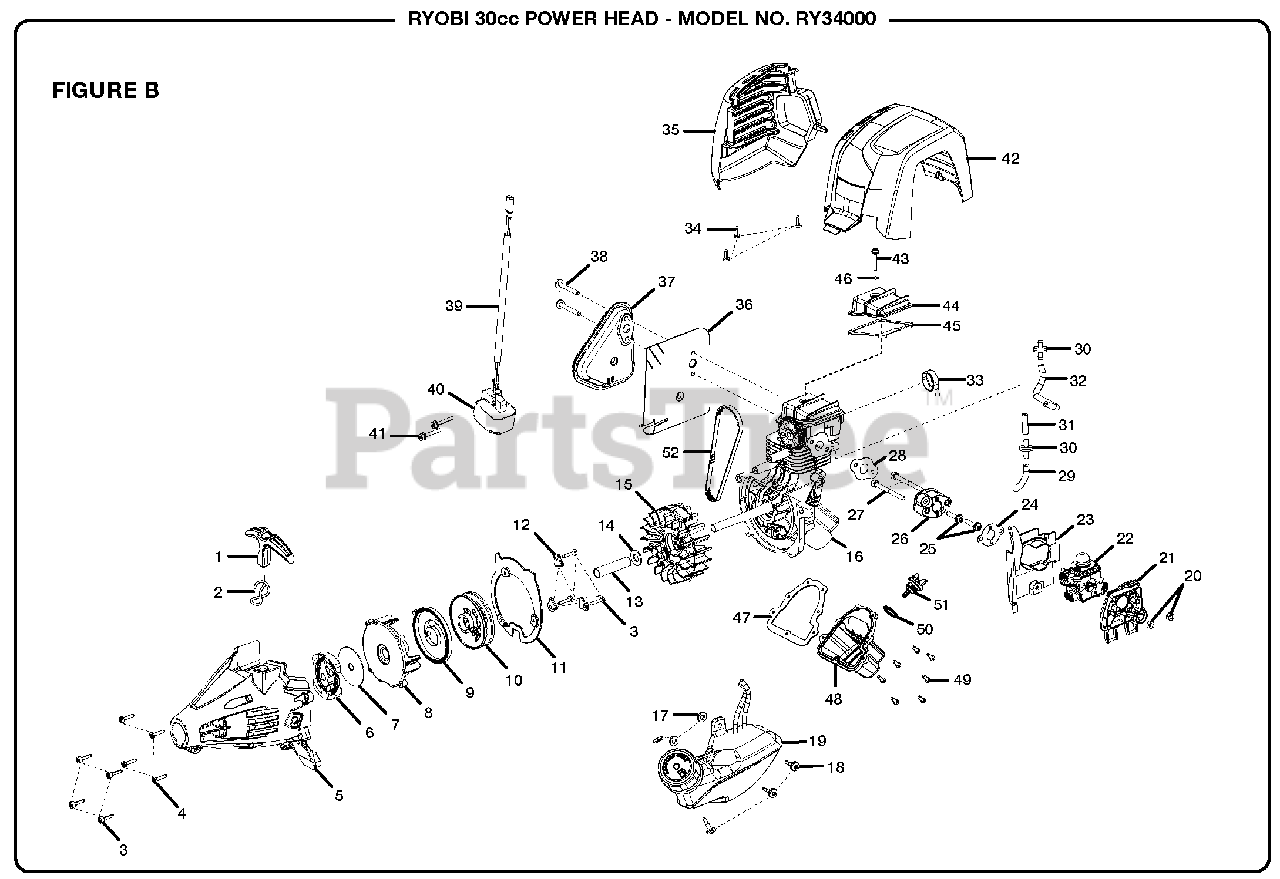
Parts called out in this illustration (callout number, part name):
1	Starter Grip
2	Starter Rope
3	Screw (M4 x 18 mm)
4	Screw (M4 x 16 mm)
5	Starter Housing Assembly
6	Clutch Assembly
8	Starter Baffle
9	Spring & Container
10	Easy Starter Assembly
12	Pulley Retainer
13	Spacer Tube
14	Washer
15	Flywheel Assembly
16	Short Block Assembly
18	Screw (M4)
19	Fuel Tank & Cap Assembly
20	Hex Nut (M5 x 0.8)
21	Air Filter Base
22	Carburetor Assembly
23	Air Baffle
24	Carburetor Gasket
25	Screw (M5 x 23 mm)
27	Bolt (M5 x 63 mm)
28	Heat Dam Gasket
29	Breather Hose
30	Check Valve
31	Breather Hose
32	Breather Hose
33	Breather Fitting
34	Screw (M4 x 12 mm)
35	Muffler Housing
36	Muffler Gasket
37	Muffler Assembly
38	Muffler Bolt (M5 x 42 mm)
39	Electrical Lead Wire Assembly
40	Ignition Module
41	Screw (M4 x 19 mm)
42	Top Cover
43	Screw (M4 x 27 mm Total, w/14 mm Threaded)
44	Cam Cover
49	Screw (M4 x 12 mm)
51	Oil Cap/Dipstick
52	Timing Belt
